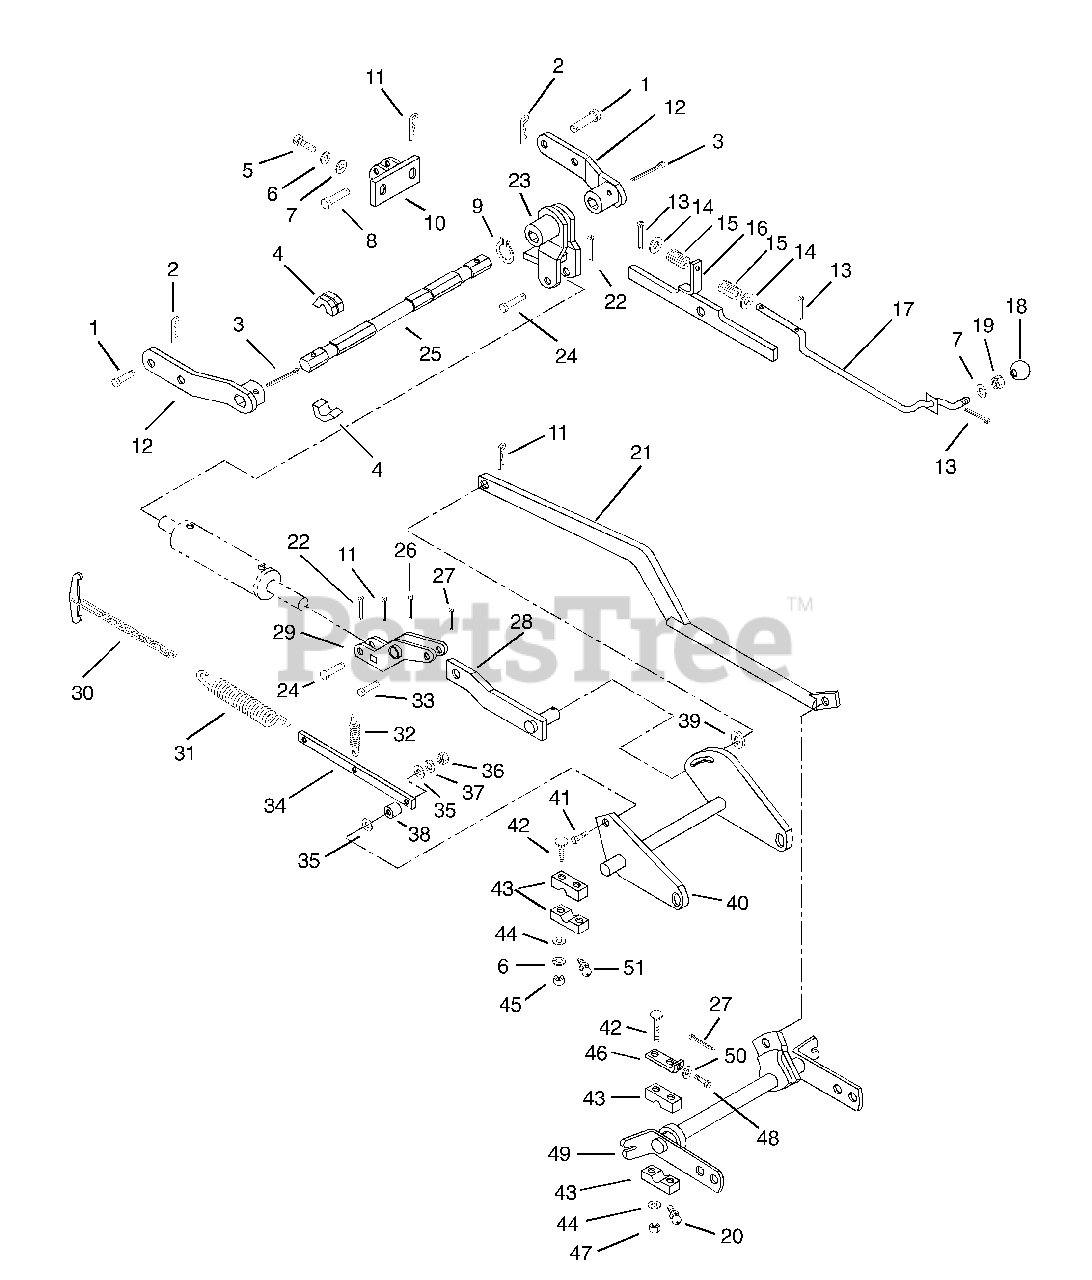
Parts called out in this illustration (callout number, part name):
1	PIN-CLEV .50X1.25 RH ST PL
2	@PIN-CTR .18X2.00 YWZC
3	PIN-COTR .18X2.0 ZCC
4	BSHG-FLG 1.000X1.750X1.000
5	@BLT-HEX .38-16X1.00 GR5 YWZC
6	@WSHR-LK .38X.094 REG YWZC
7	@WSHR-FL-STL.438X1.00X.083 YWZ
8	PIN-CLEV .619X2.0 YWZC
9	RG-RTNG-EXT 1.125X.050
11	PIN-HAIR-INT .09X.188X2.00YWZC
13	@PIN-CTR .12X.75 EXTPRSQCT YWZ
14	@WSHR-FL-STL.406X.812X.065 YWZ
15	SG-COMP .65X.56X1.50
17	LATCH ROD
18	KNOB-STEERING LOCK
19	NUT-HEX-JAM .375-16 YWZC
20	FTG-LUBE .25-28X.256 YWZC
21	LINK - CONNECTOR
22	@PIN-CTR .12X1.00 EXTPRSQCT YZ
24	PIN-CLEV .494X1.94 YWZC
26	@PIN-CTR .18X1.25 EXTPRSQCT YZ
27	@PIN-CTR .18X1.00 EXTPRSQCT YZ
29	BELLCRANK
31	SG-TENS .156X1.062X8.68 WLD ??
32	SG-TENS .035X.45X2.75 WLD 3.5
33	PIN-CLEV .619X1.43 YWZC
35	@WSHR-FL-STL.281X.62X.065 YWZC
36	@NUT-HEX .25-20 YWZC
37	WSHR-LK .250X.077 HVY YWZC
38	SPACER .269X.375X.343
39	@WSHR-FL-STL.812X1.50X.135YWZC
40	CENTER ROCKSHAFT
41	@BLT-HEX .25-20X1.00 GR5 YWZC
42	@BLT-RDHDSQNK .38-16X2.25 G5YZ
44	WSHR-FL-STL .406X.750X.005 YWZ
45	@NUT-HEX .38-16 YWZC
47	@NUT-LK-CTR .38-16 YWZC
48	@BLT-HEX .31-18X1.25 GR5 YWZC
49	ROCK SHAFT-FRONT
50	WSHR-LK .312X.097 HVY YWZC
